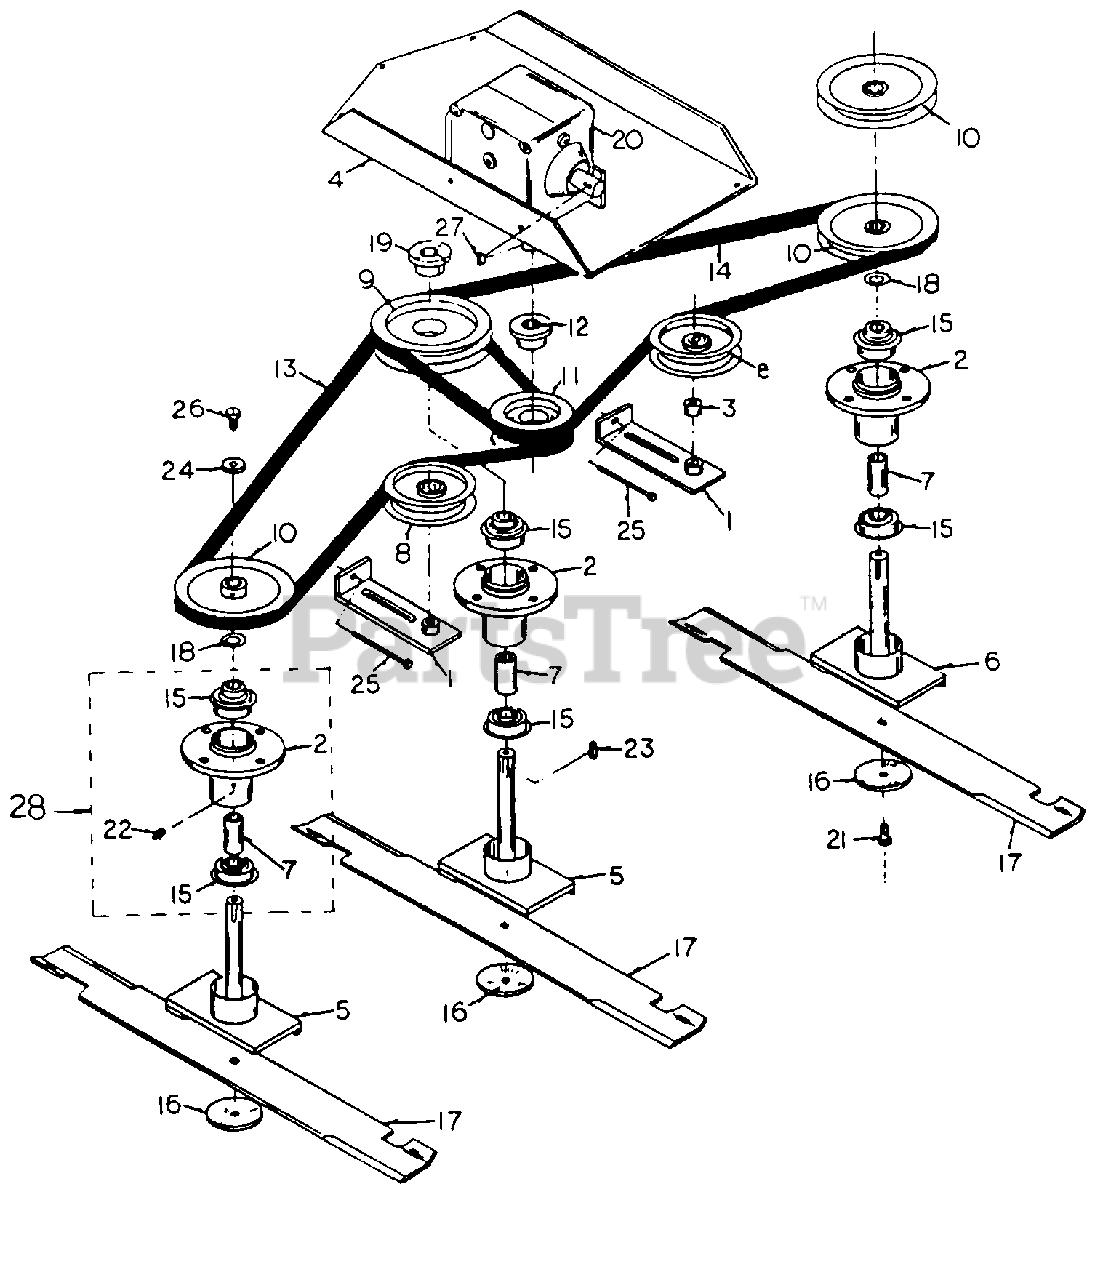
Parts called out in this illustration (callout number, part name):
1	Belt Tightener
2	Housing Spindle
3	Spacer
4	Gearbox Mount
5	Short Spindle Shaft
6	Long Spindle Shaft
7	Spindle Shaft Spacer
9	Double Pulley, 4.6"
10	Single Pulley, 5"
11	Double Pulley, 4.2"
14	Belt, B x 58
15	Spindle Bearing, 7/8"
18	Mech. Washer, 14GA
19	Taper Hub, 7/8"
21	Bolt, 3/8-24 x 1-1/4", GR5
23	Key Stock, 3/16" x 3/16" x 1"
24	Spindle Washer, 5/16", 10 GA 0
25	Hex Tap Bolt, 1/4-20 x 4"
26	Hex Capscrew, 5/16-24 x 3/4", GRS
27	Woodruff Key, 1/4" x 7/8"
28	Spindle Houslng Assembly
